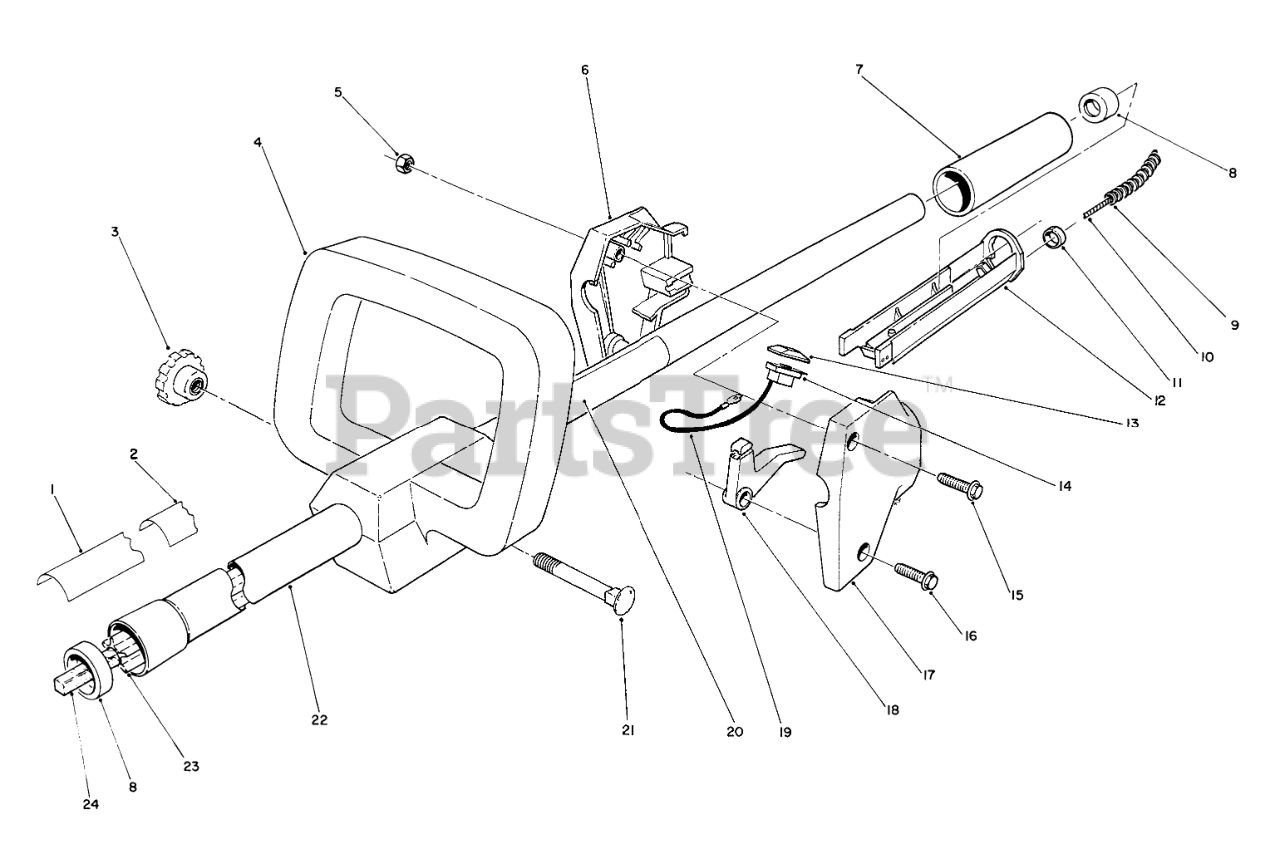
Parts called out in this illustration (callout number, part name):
1	DECAL - TC 3105
2	DECAL - WARNING
4	HANDLE SECONDARY
5	NUT-LOCK, NI
6	RH HOUSING
7	GRIP - RUBBER
8	CASING RETAINER
9	CABLE COVER
10	THROTTLE CABLE
11	RING FITTING
12	TROUGH 1"
13	SWITCH COVER
14	SWITCH
16	SCREW-SHOULDER
17	LH HOUSING
18	THROTTLE LEVER
19	WIRE ASM
20	DECAL-INSTRUCTION
21	BOLT-CARRIAGE
22	SHAFT HOUSING TUBE
23	SHAFT SPACER
24	DRIVE SHAFT
